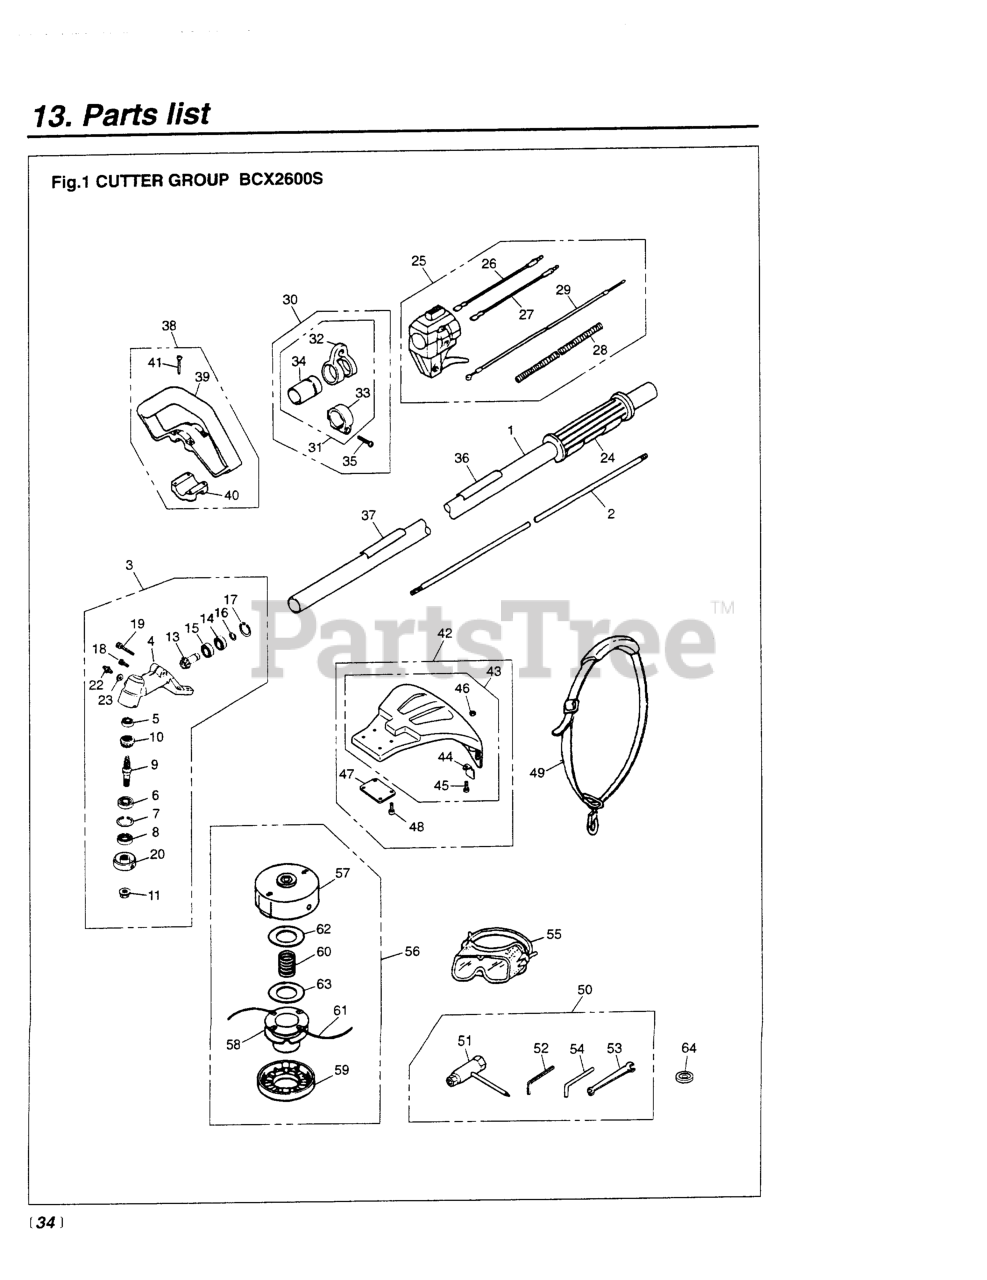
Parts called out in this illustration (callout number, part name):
3	GEARCASE ASSY (RPLS -13000)
4	GEARCASE
5	BEARING (RPLS T3300-13521)
6	BEARING (RPLS T3403-13510)
7	RING, SNAP, M26 X 1.2
8	SEAL, OIL
9	SHAFT
10	GEAR
11	NUT
13	PINION
14	BEARING (RPLS T3300-13531)
15	BEARING (RPLS T3403-13530)
16	RING, SNAP (RPLS T3300-13330)
17	RING, SNAP, M24 x 1.2
18	BOLT, M5 X 10
19	BOLT
20	HOLDER (A)
22	FITTING, GREASE
23	WASHER, M6 X .8
24	GRIP (RPLS 3577-32140 & 3220-
26	CORD (A), BLACK
27	CORD (B), RED
28	TUBE (RPLS 4900-72141)
29	CABLE (RPLS 5580-83100)
30	HANGER ASSEMBLY
31	HANGER COMPLETE
32	HANGER
33	CLAMP
34	SLEEVE
36	PLATE, NAME (BCX2600DL)
37	PLATE, CAUTION
38	HANDLE ASSEMBLY
39	HANDLE
42	GUARD ASSY (RPLS -24000)
43	GUARD COMP (RPLS. -24100)
44	BLADE (RPLS T3002-24120)
46	NUT
47	PLATE
48	BOLT (USE 3310-31720)
51	SOCKET
52	WRENCH (TOOL)
53	SPANNER, 8 X 10 (RPLS 2540- )
54	BAR
55	GOGGLE
56	4
57	CASE (RPLS -15112)
58	HOLDER, CORD (RPLS -15141)
59	COVER (RPLS -15130)
60	SPRING (RPLS -99161)
61	CORD
62	PLATE, LARGE
63	PLATE, SMALL
64	HOLDER (B)
